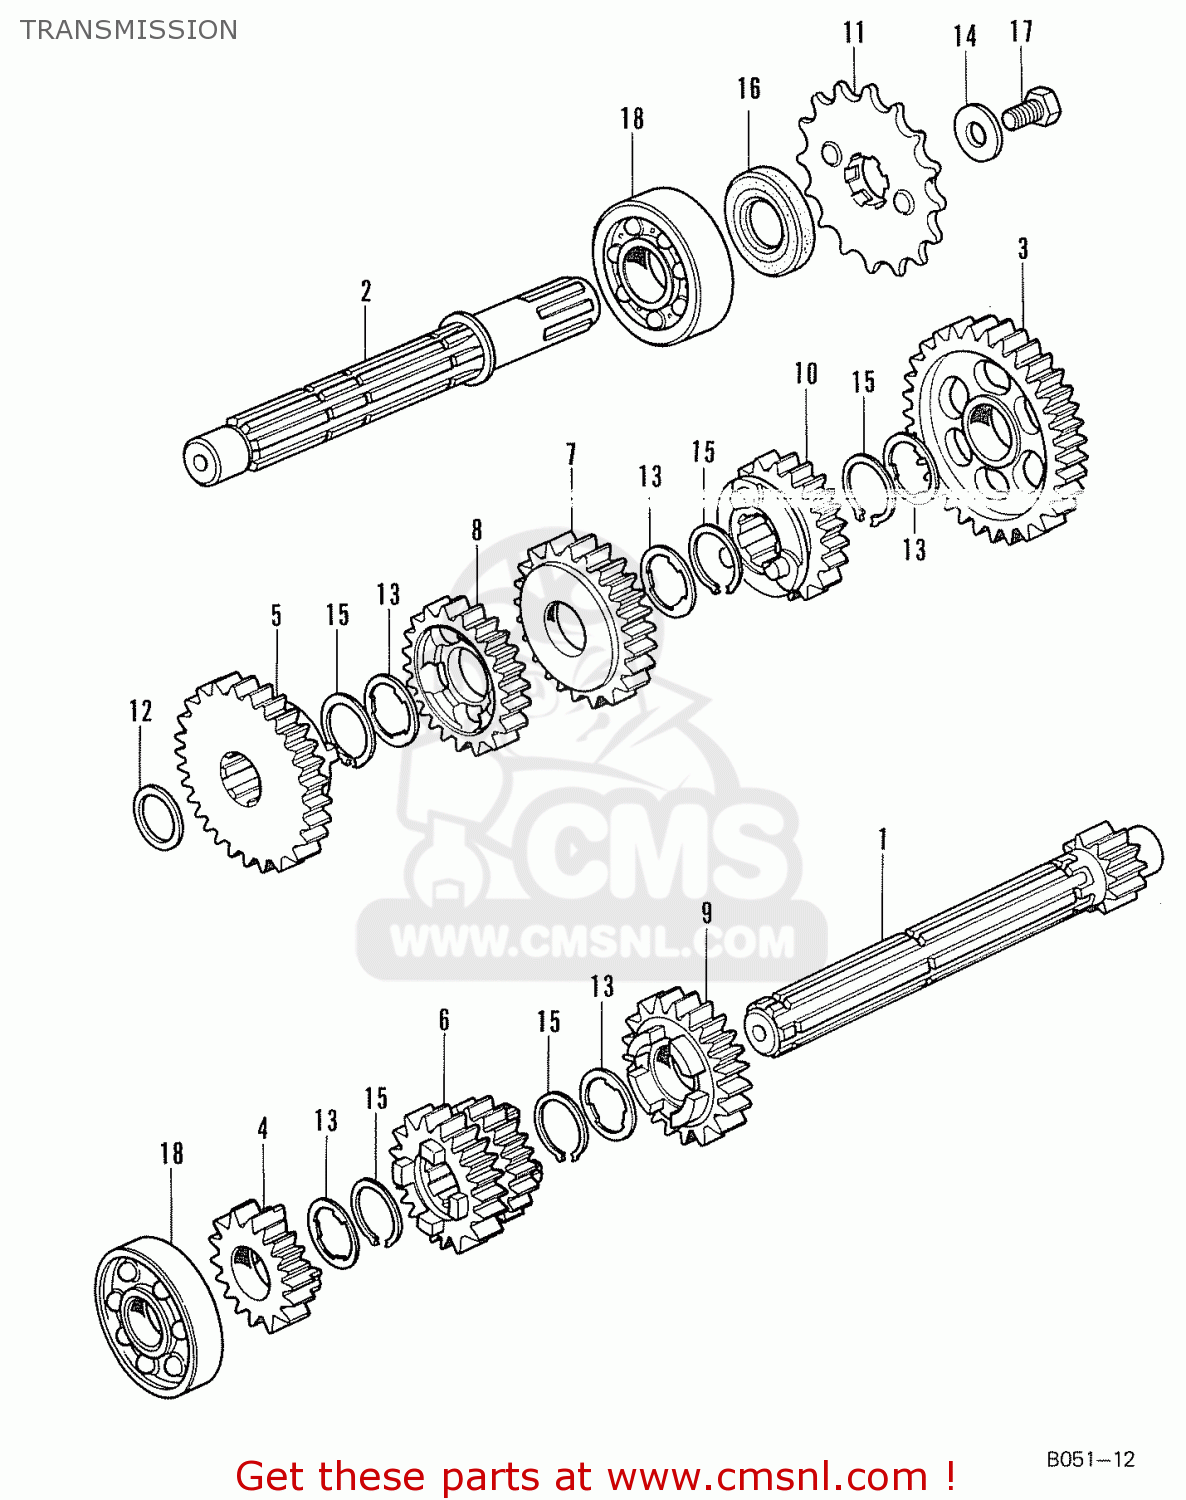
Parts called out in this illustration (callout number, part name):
1	SHAFT MISSIONMAIN
2	SHAFT,COUNTER
3	GEAR, LOW
4	GEAR,2ND.
5	GEAR,2ND.
6	GEAR THIRD
7	THIRDGEAR COUNTER
8	GEAR, 4TH
9	GEAR, TOP
10	TOPGEAR COUNTER
11	SPROCKET 13T
12	WASHER 13.5 MM
13	WASHER,SPLINE
14	WASHER, 14M/M
15	CIRCLIP, 17M/M
16	SEAL,17 X 19 X5
17	BOLT, HEX., 8X14
18	B/BRG RAD N/COM
